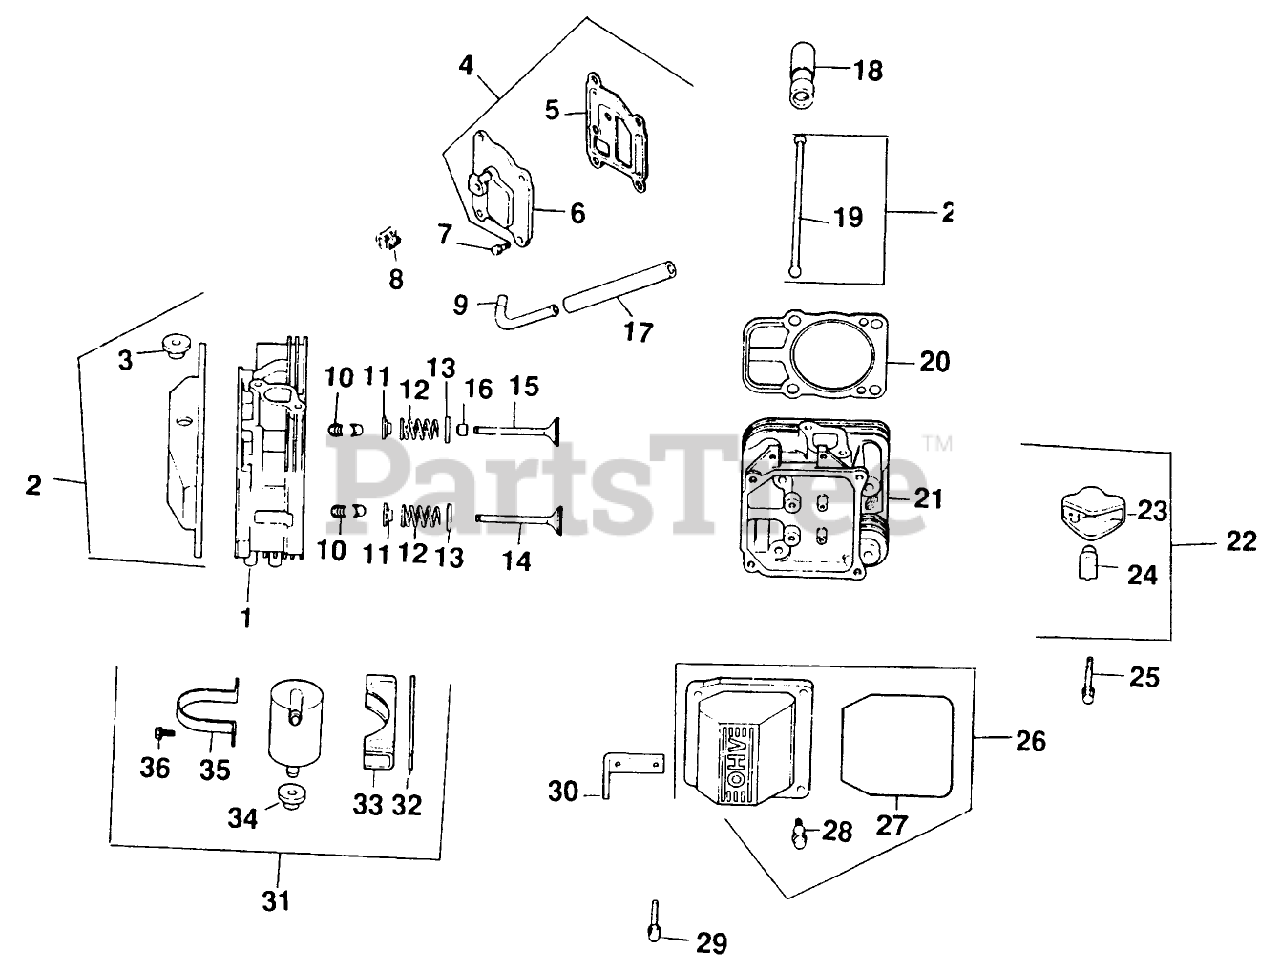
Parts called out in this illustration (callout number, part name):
1	#1 Cyl. Head Asm
2	Kit-Valve Cover/Breather (Incl. Ref. #3 & 27-28)
3	Grommet-Rubber
4	Kit-Breather Cover Gasket (Incl. Ref. #5-6)
5	Gasket-Breather
6	Cover-Breather
7	Screw
8	Plug
9	Fitting
10	Retainer Kit
11	Cap-Spring, Valve
12	Spring-Valve
13	Retainer-Spring
14	Valve-Exhaust
15	Valve-Intake
16	Seal-Stem, Valve
17	Hose
18	Lifter-Valve
19	Rod-Push
20	Gasket-Cylinder Head
21	#2 Cyl. Head Asm,
22	Kit-Valve Train (Incl. Ref. #19 & 23-24)
23	Arm-Rocker
24	Pivot-Arm, Rocker
25	Screw
26	Kit-Valve Cover (Incl. Ref. #27-28)
27	"O"Ring
28	Screw
29	Screw
30	Strap-Lifting
31	Kit-Breather Separator (Incl. Ref. #32-36)
32	Spacer
33	Bracket
34	Grommet
35	Strap-Lifting
36	Screw
